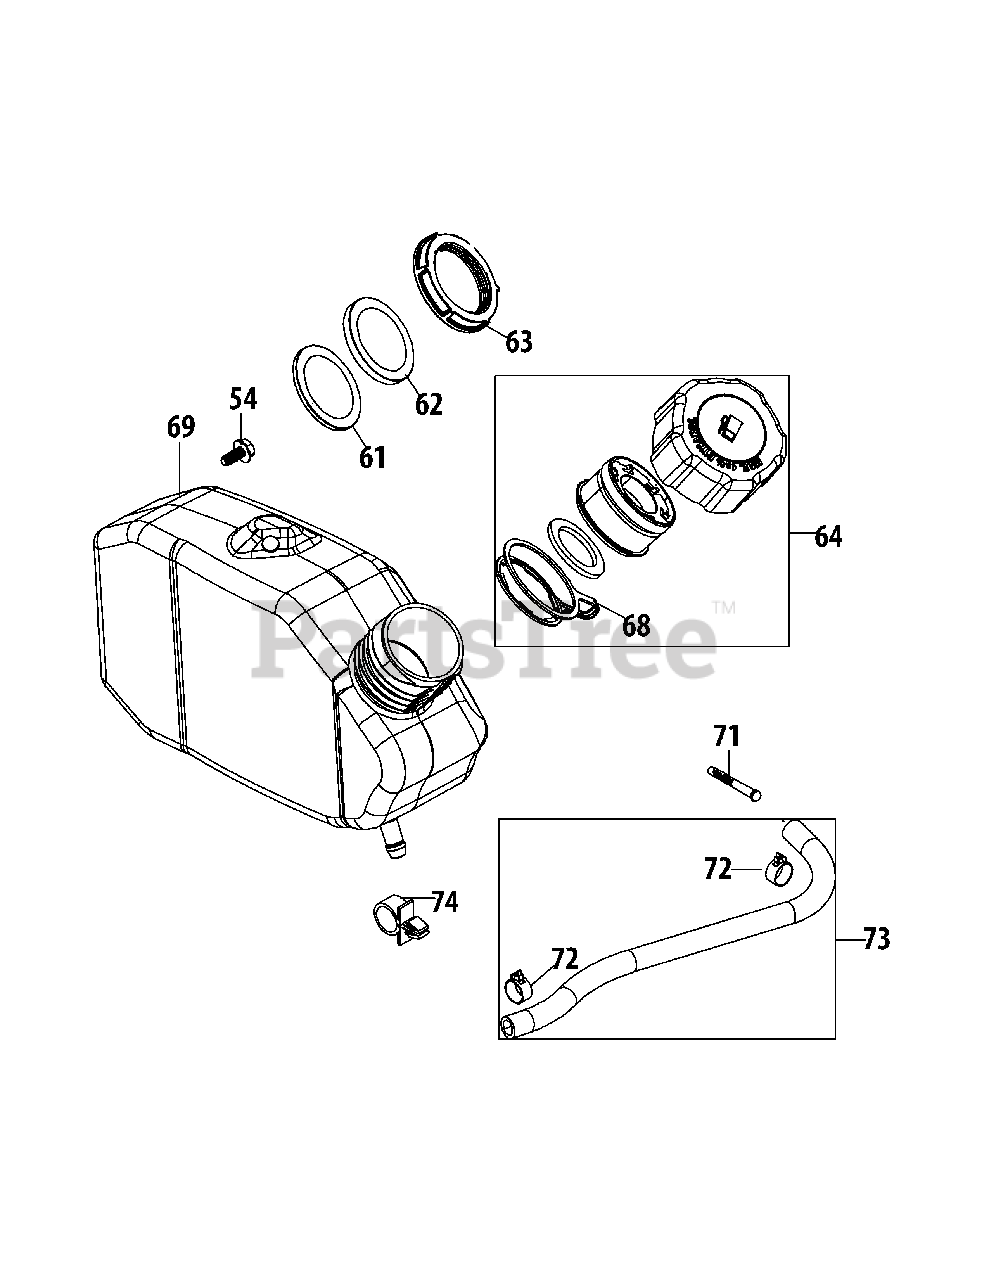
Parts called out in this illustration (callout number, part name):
54	Bolt M6X14 Multi-Purpose
61	Fuel Tank Lower Grommet
62	Fuel Tank Upper Grommet
63	Fuel Tank Nut
64	Fuel Cap Assembly
68	Fuel Cap Tether
69	Fuel Tank
71	Fuel Filter
72	Fuel Hose Clamp
73	Fuel Hose
74	Plastic Support Clamp
